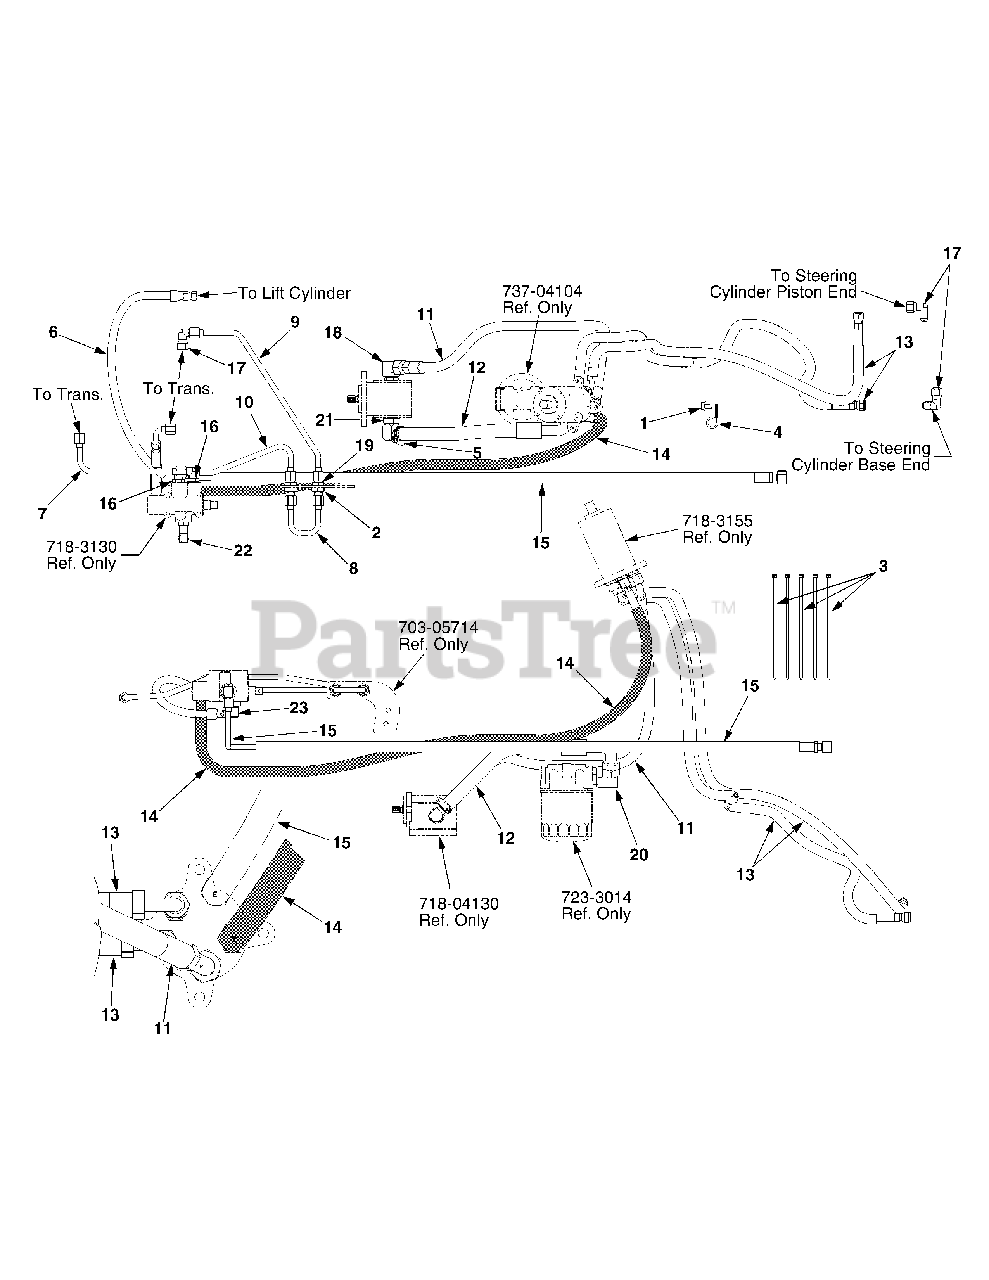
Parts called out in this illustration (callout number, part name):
1	Screw, Hex Wash Hd Tapp, 5/16-18 x .5
2	Nut, Hex Jam, 9/16-18 GR5
3	Tie, Cable
4	Clamp, Hose
5	Clamp, Adjustable Hose
6	Hose, Lift Cylinder
7	Tube, Cylinder Return
8	Tube, U Return
9	Tube, Return Tank
10	Tube, Return
11	Hose, Steering Pressure
12	Hose, Aux. Pump-Filter
13	Hose, Steering
14	Hose, Steering - Tank
15	Hose, Lift Inlet - w/45 degree Hydraulic Fitting at Steering Pump
15	Hose, Lift Inlet - w/Straight Hydraulic Fitting at Steering Pump
16	Fitting, 90 Degree
17	Fitting, 90 Degree Swivel
18	Fitting, 90 Degree
19	Fitting, Bulkhead
20	Fitting, 90 Degree
21	Fitting, 10 Orb:5/8 tube
22	Fitting, 90Degree
23	Fitting, 90 Degree
